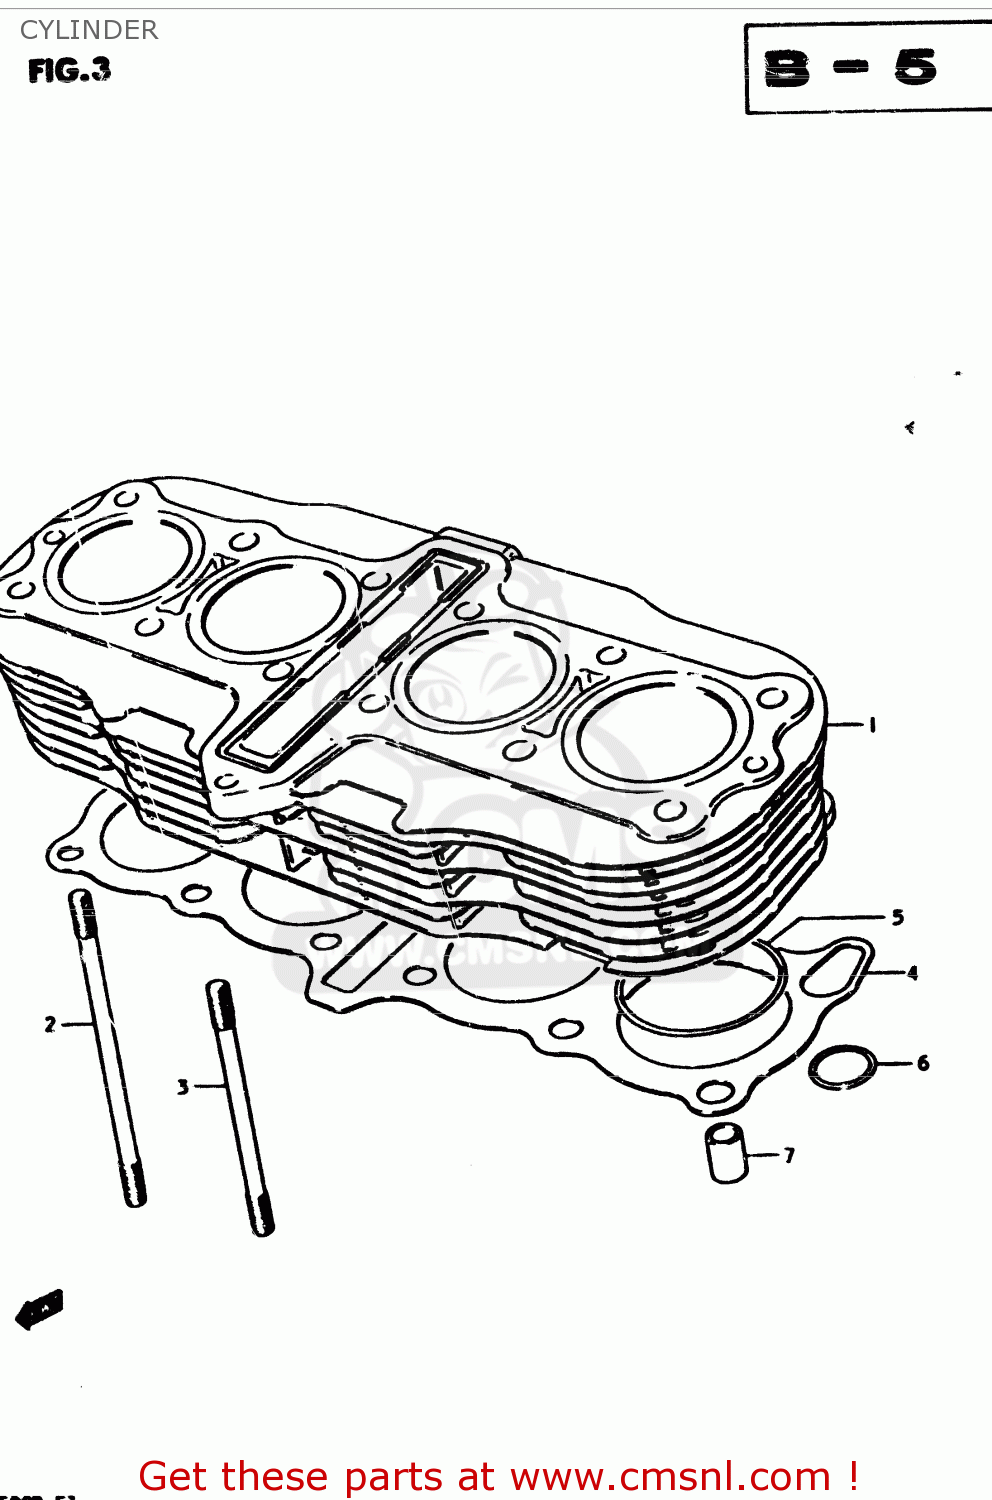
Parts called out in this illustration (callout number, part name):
1	CYLINDER
2	BOLT,STUD
3	STUD
4	GASKET,CYLINDER (MCA)
5	O RING(D:2,ID:70)
6	O RING(D:3.05)
7	PIN
